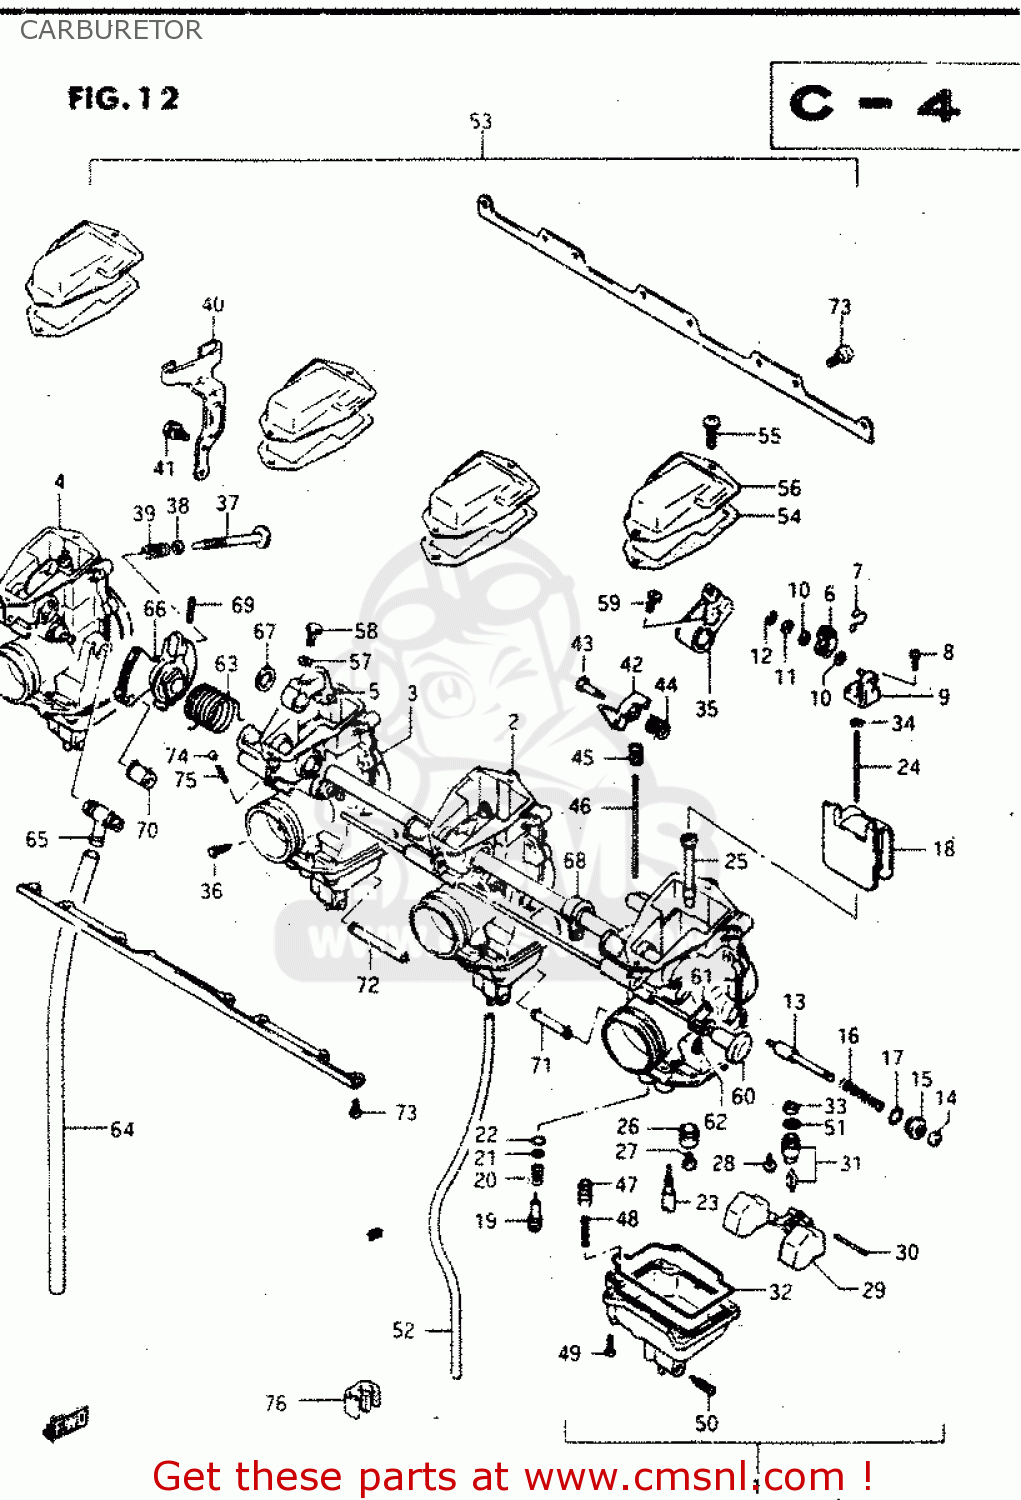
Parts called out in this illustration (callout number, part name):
1	CARBURETOR ASSY, LH
2	CARBURETOR ASSY, ML
3	CARBURETOR ASSY, MR
4	CARBURETOR ASSY, RH
5	ARM,THROTTLE
6	PLATE
7	SPRING
8	SCREW
9	CONNECTOR
10	GASKET (NAS)
11	WASHER
12	E-RING
13	PLUNGER
14	CAP,STARTER VALVE
15	GUIDE SCREW,PLUNGER
16	SPRING
17	O RING
18	VALVE, PISTON
19	SCREW,PILOT
20	SPRING
21	GASKET
22	O-RING
23	JET,PILOT(32.5)
24	NEEDLE, JET
25	JET,NEEDLE(P-5)
26	RING,MAIN JET FIXING
27	JET,MAIN(97.5)
28	SCREW
29	FLOAT
30	PIN,FLOAT
31	VALVE ASSY,NEEDLE
32	O RING,FLOAT CHAMBER
33	FILTER
34	CLIP
35	LEVER ASSY
36	SCREW
37	SCREW,THROTTLE STOP
38	WASHER
39	SPRING
40	BRACKET
41	SCREW
42	LEVER
43	BOLT
44	SPRING,PLUNGER
45	BOOT, ACCELE PUMP ROD
46	ROD
47	PLUNGER
48	SPRING
49	SCREW
50	SCREW,DRAIN
51	O RING
52	HOSE SET (3X5X525)
53	FLANG SET
54	GASKET,CARBURETOR TOP (NAS)
55	SCREW
56	COVER,CARBURETOR,TOP
57	WASHER
58	BOLT
59	SCREW
60	SHAFT ASSY
61	LEVER
62	SCREW,THROTTLE ADJUST
63	SPRING
64	HOSE
65	NIPPLE
66	LEVER ASSY
67	RING,THROTTLE SHAFT
68	SHAFT ASSY
69	PIN,THROTTLE SHAFT
70	HOSE SET (3X5X18)
71	HOSE SET (3X5X60)
72	HOSE SET (3X5X72)
73	SCREW
74	BALL,CARBURETOR
75	SPRING
76	CLIP
